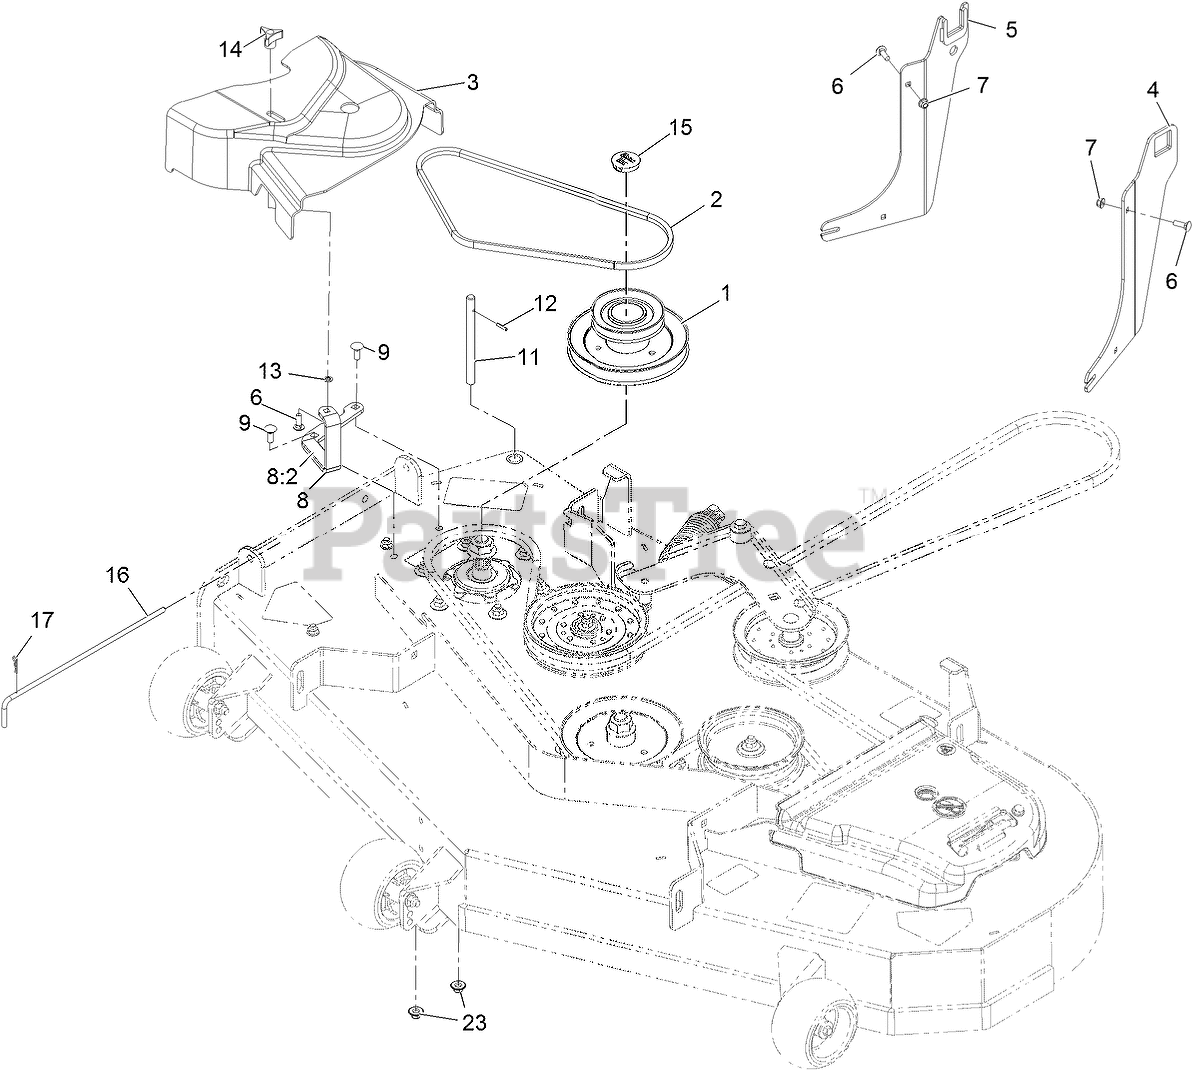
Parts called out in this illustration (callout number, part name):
1	JACKSHAFT-UV DRIVE 52 SPL
2	BELT-BLOWER
3	COVER-BELT, UV 52
4	BRACKET ASM, LH
5	BRACKET ASM, RH
6	BOLT-CARR
7	NUT-HF, NI
8	ASM-CVR BRKT W/DECAL
8:2	DECAL-DANGER
9	BOLT-CARR
11	SHAFT-CATCHER, GRASS
12	PIN-ROLL
13	RING-RETAINING, BOLT
14	KNOB-3 PRONG
15	PLUG, BLACK NYLON 1.75
16	PIN,CHUTE PIVOT
17	PIN-COTTER
23	Nut-Nyloc 3/8-16 Flg
